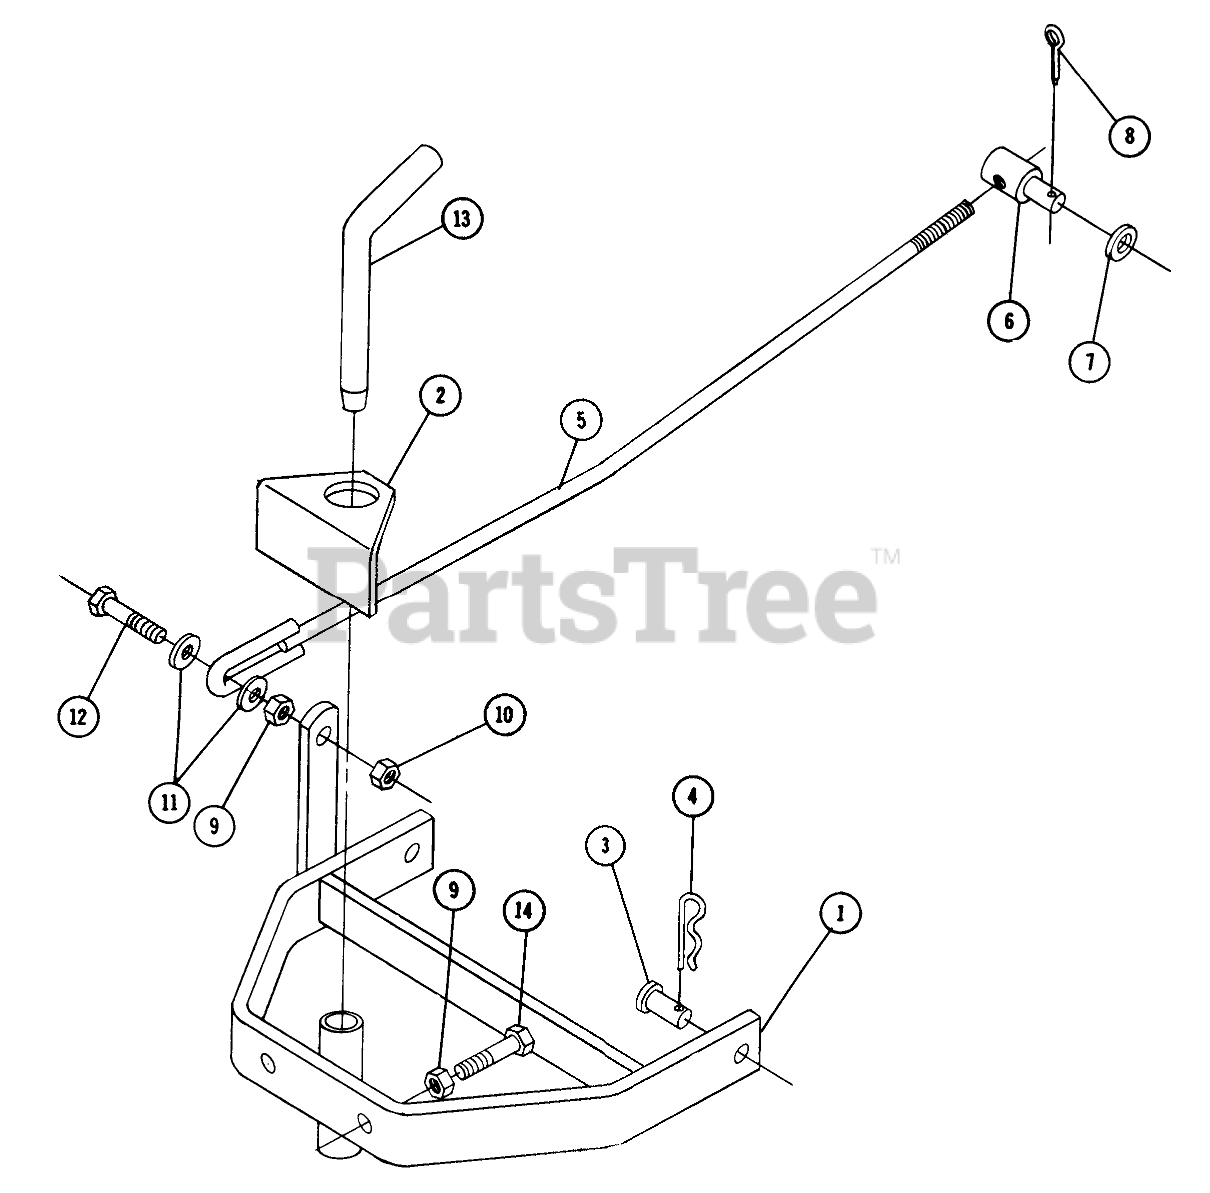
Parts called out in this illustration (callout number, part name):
1	Hitch
2	PLATE ADJ HITCH R
4	Hairpin-Cotter
5	Rod-Hitch
6	ROD-TRUNNION LIFT
7	Washer
8	Cotter Pin
9	Nut-1/2-13
10	Locknut-1/2-13
11	Washer-Flat
12	Bolt-Hex 1/2-13 x 2
13	Hitch Pin
14	Bolt 1/2-13 x 2
